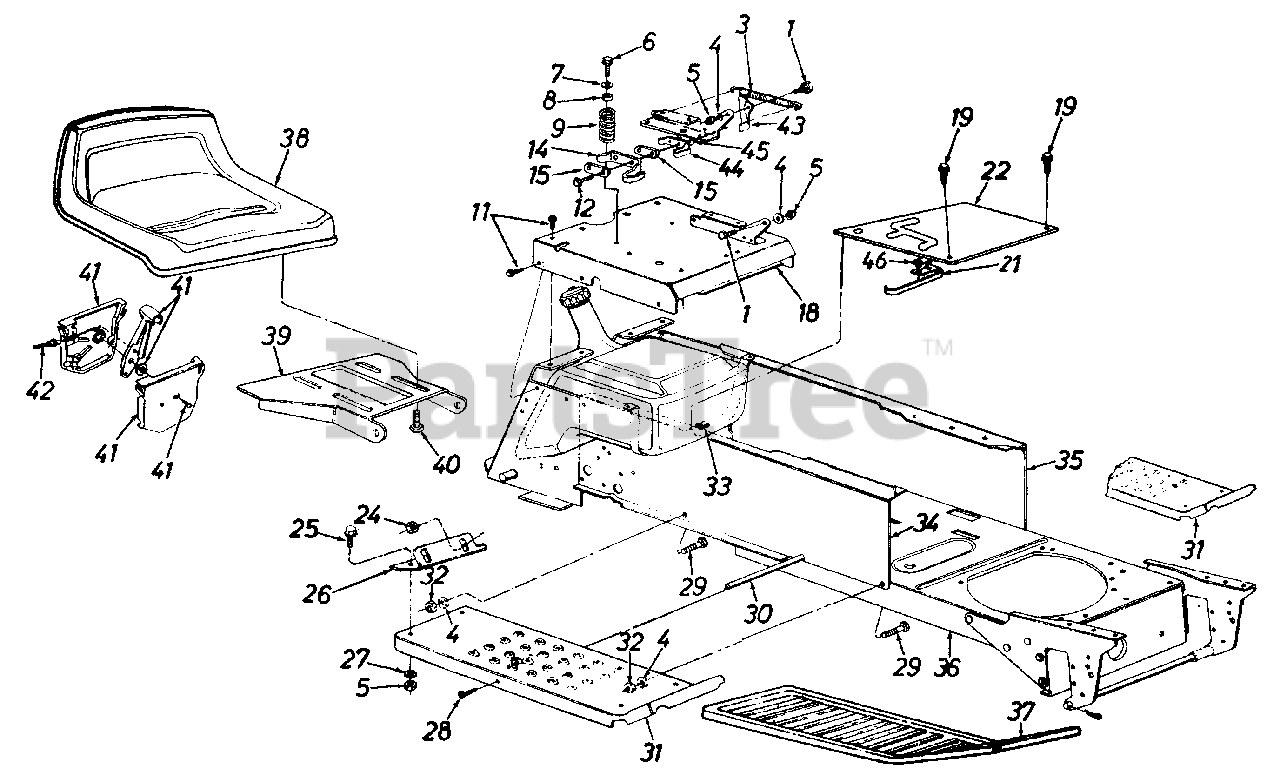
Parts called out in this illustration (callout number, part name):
1	Shld. Bolt .437" Dia. x .162"
3	Ext. Spring 5.31" Lg.
4	L-Wash. 5/16" I.D.
5	Hex Nut 5/16-18 Thd. (Gr. 5)
6	Hex Wash. Hd. Tap Scr. 5/16 -18 x .7" Lg.
7	Fl-Wash. .344" I.D.
8	Bushing
9	Compression Spring
11	Hex Wash. Hd. AB-Tap Scr. 5/16 x .75" Lg.
12	Hx Wash. Hd. AB-Tap Scr. #8 x .5" Lg.
14	Spring Switch
15	Insulator Plate
18	Seat Plate
19	Truss Mach. B-Tap Scr.
21	Reverse Safety Switch
22	Shift Cover
25	Hex Bolt 5/16-18 x .75" Lg.
28	Truss Mach. Scr. 5/16-18 x .75" Lg.
29	Rib Neck Bolt 5/16-24 x .75" Lg.
30	Running Board Rod
33	Speed Nut #10Z
38	Seat 8-7/8" High
40	Hex Tap Scr. 3/8-16 x .62" Lg.
41	Throttle Control Box Ass'y.
42	Throttle Control Wire 35" Lg.
43	Seat Lift Bracket
44	Seat Spring Switch
45	Insulator Boss Plate
46	Insulator Nut Plate
